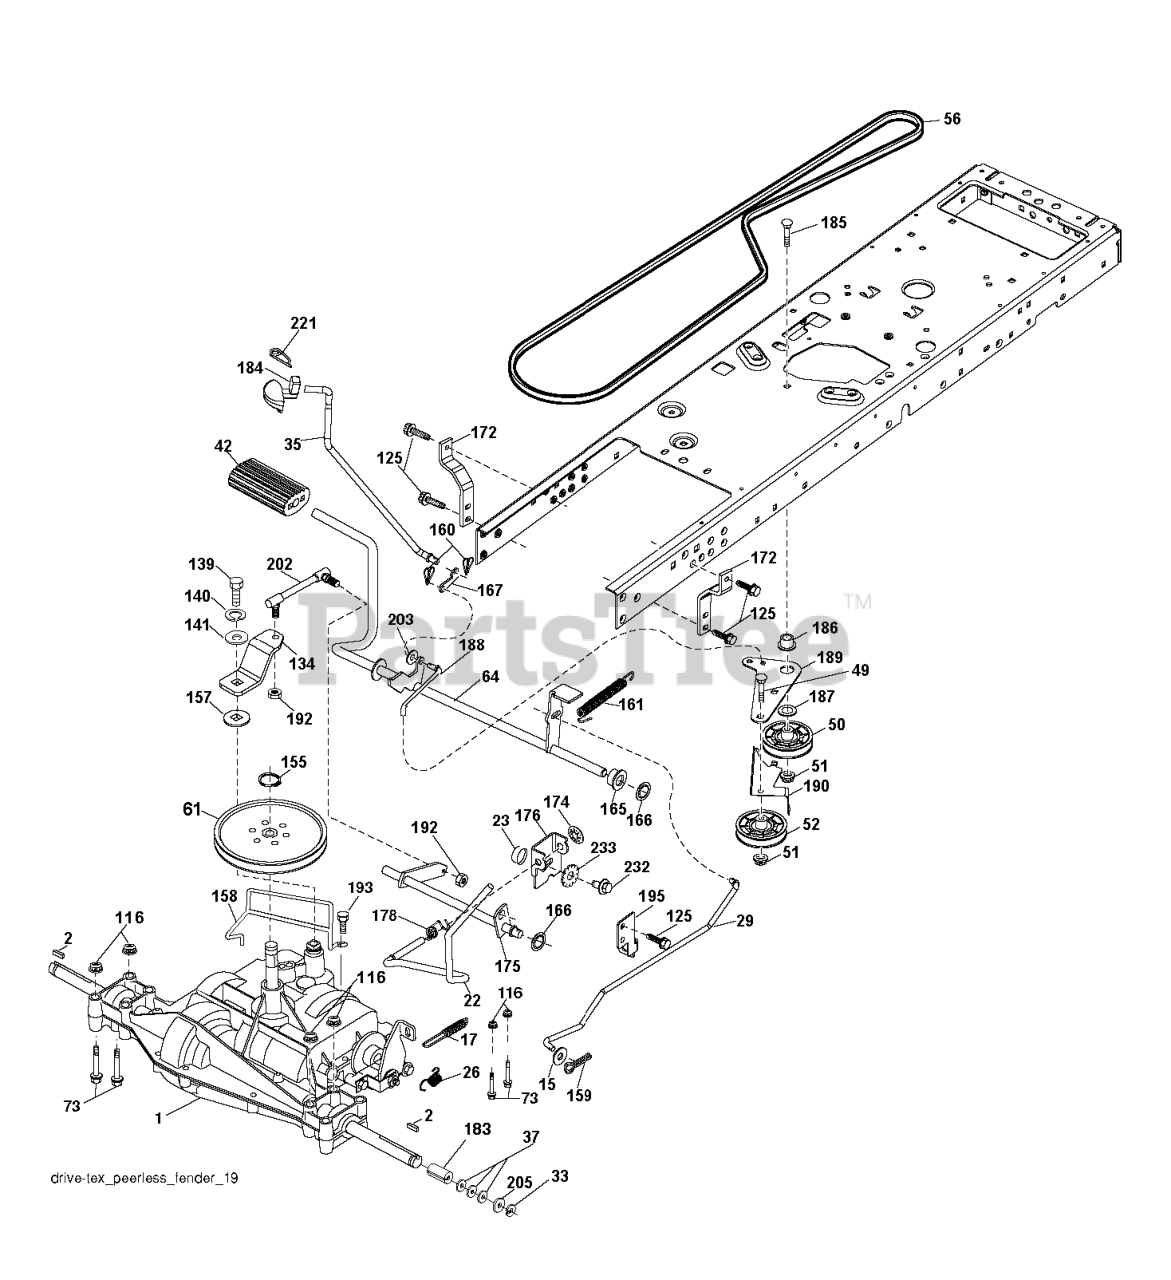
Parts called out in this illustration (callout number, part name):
2	SQUARE KEY
15	WASHER
17	SPRING.BRAKE.PEERLESS.TEX
22	ROD.SHIFT.FENDER.TLT.2006
23	KNOB.DUCKHEAD.1/2
26	SPRING.BRAKE.RTN.GR.DR
29	ROD.BRAKE.PEERLESS
35	ROD.CNTRL.PARK.PREDATOR.LT.TEX
42	PEDAL COVER T
50	IDLER.FLAT.910.OFFSET
51	NUT LOCK FLG 3/8-16 UNC
52	IDLER.V-GROOVE.910.OFFSET
56	V-BELT.TRACTOR.DRIVE.P
61	PULLEY TRANS
64	SHAFT.ASM.PEDAL.BRAKE.
73	BOLT HEX 5/16-18 GR 5
116	NUT LOCK HEX FLANGE 5/16-18
125	SCREW
139	BOLT 1/4-28X3/4
140	LOCKWASHER
155	RETAINING RING LT
157	WASH-SHFT PLT LT
158	KEEPER.PMS.18/20.D4365
159	COTTER PIN
160	RETAINER CLIP
161	SPRING, RETURN LT
165	BUSHING.SHAFT.BRAKE.HAND
166	NUT.PUSH.625.2006
167	LATCH.BRAKE.SPRING
172	STRAP.TRQ.LH.GEAR.DRIV
174	NUT.PUSH.500.2006
175	SHAFT ASM SHIFT
178	SPRING.SHIFT.GT2006
183	SPACER AXLE
184	HANDLE PARKING BRAKE
186	SPACER.RETAINER
187	WASHER 12/32X2X10GA
188	RP.LINK.CLUTCH.GROUND.DRIVE
189	BELLCRANK.GROUND.DRIVE.TEX.
190	KEEPER.BELLCRANK.DRIVE
192	NUT LOCK CENTER 1/4 -28 FNTHD
193	SCREW 5/16"
195	BRKT.ROD.BRAKE.PEERLES
202	LINK.SHIFT.PMST.18" (SPG1286)
203	WASHER
221	RETAINER.SPRING.CLIP.H
226	BOLT FIN HEX 7/16-14 X 1
227	WASHER SERRATED
